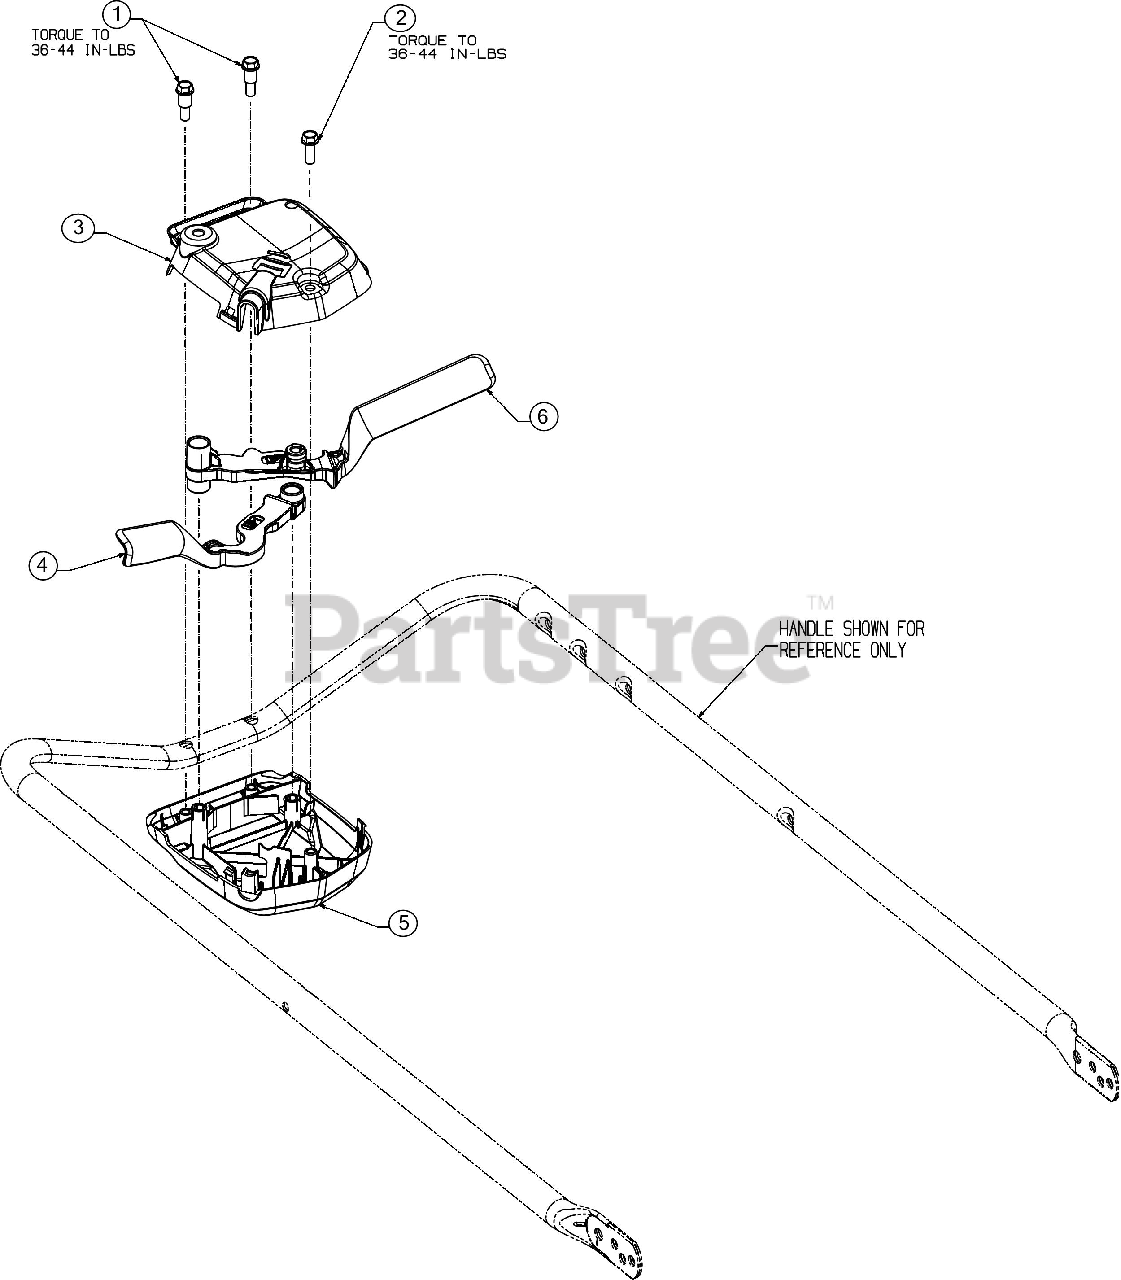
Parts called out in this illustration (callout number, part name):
1	SHOULDER SCREW 1/4-15 x .970
2	SCREW 1/4-15 x .750
3	LOWER CONTROL HOUSING
4	CONTROL LEVER (LH)
5	UPPER CONTROL HOUSING
6	CONTROL LEVER (RH)
